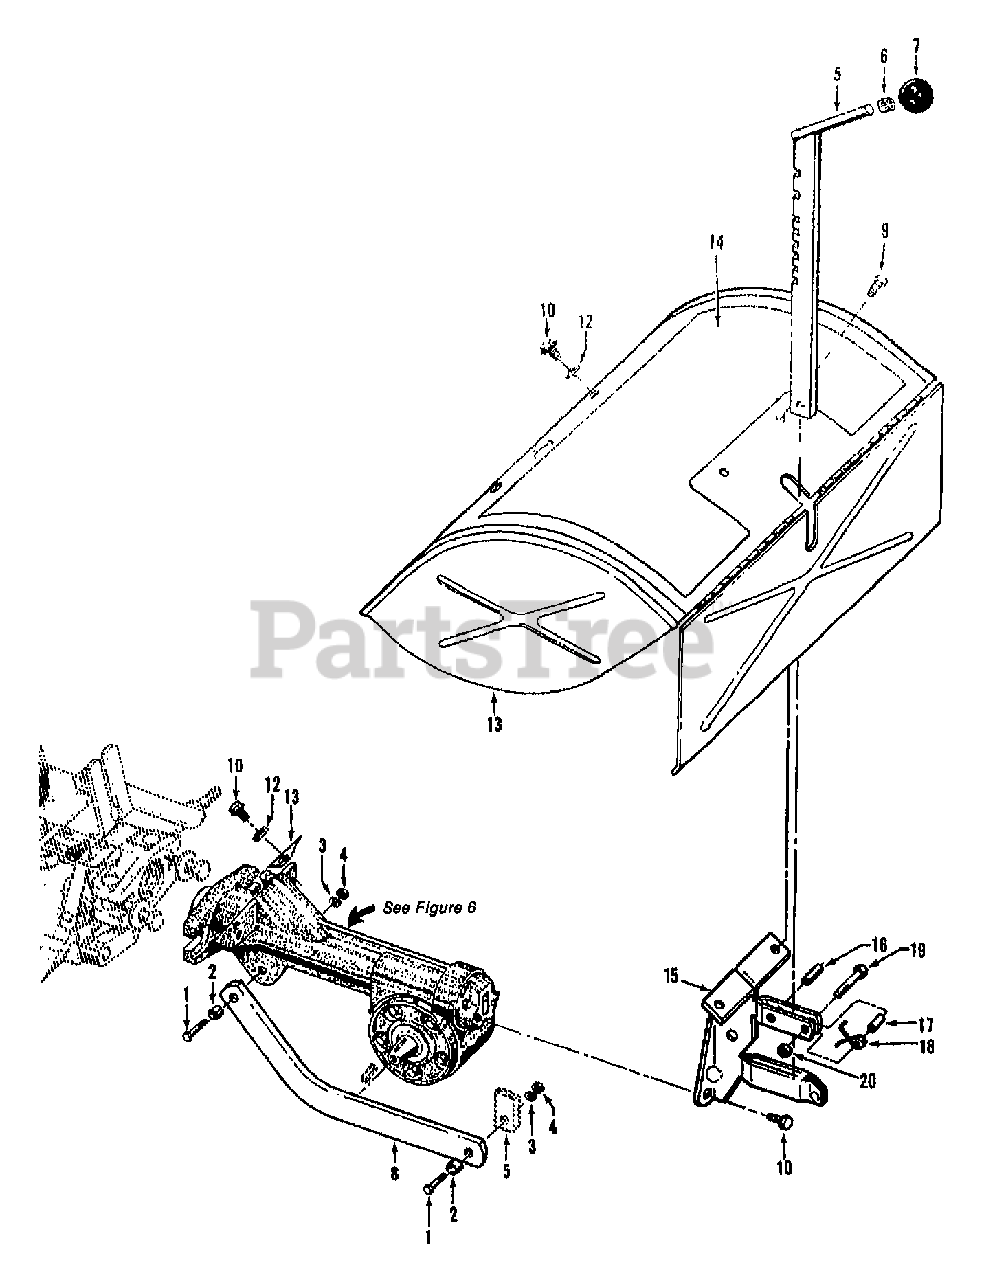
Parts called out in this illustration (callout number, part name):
1	SCR-HH 3/8-16X1.25
2	BUSHING-.5X.375X.3
3	WASHER-LK .375
4	NUT-HEX 3/8-16 ZP
5	DEPTH REGULATOR W/KNOB
6	RING-TOLERANCE .5325 ID
7	KNOB-CONTROL
8	BAR-DRAG RED
9	SCR-HWH 1/4-20 X .5 STH
10	SCR-HFLK 5/16-18X.75 ZP
12	WASHER-#1.125X.344 ZP
13	HOOD W/DECALS OPC SERVICE (REF.#14)
14	DECAL-HOOD INST
15	BRKT W/ROLL PIN (9308) (REF.#16)
16	PIN-ROLL .25 X 1 (SPIROL)
17	SPACER-.250X.343X.375
18	SPRING-TORSION
19	SCR-HH 1/4-20X1.0
20	NUT-LK 1/4-20
